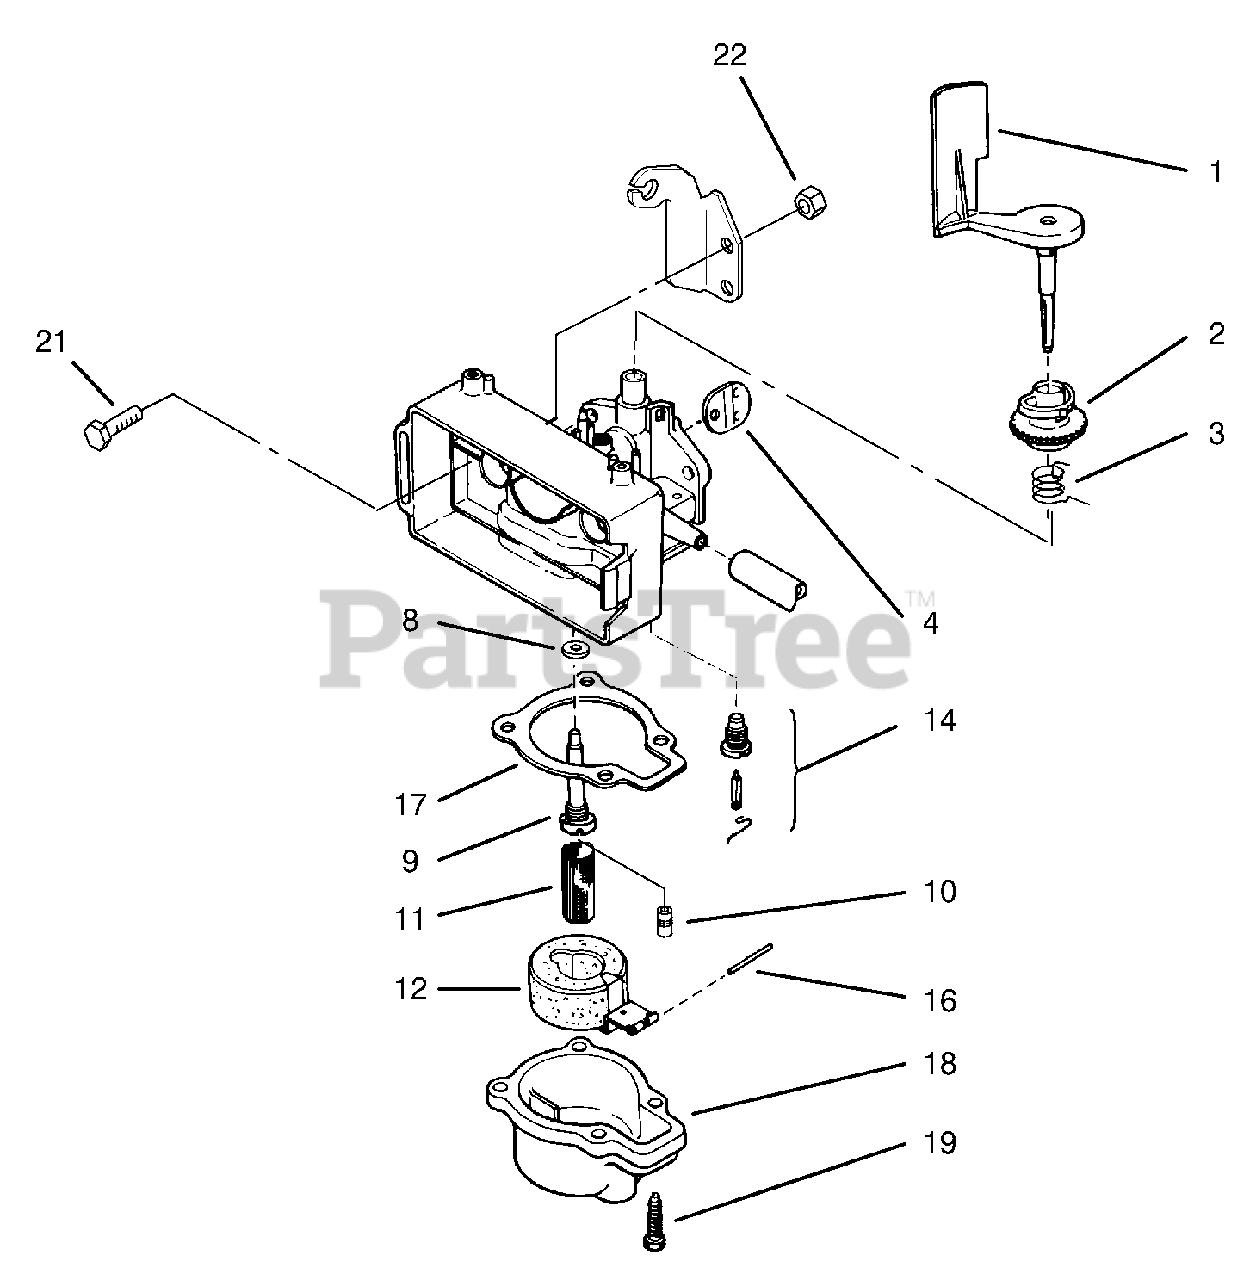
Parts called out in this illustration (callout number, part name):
1	Airvane And Shaft
2	Collar-Adjust, Airvane
3	Spring-Throttle
4	Disc-Throttle V
8	Washer Xvs
10	Jet-Main
11	Filter-Fuel Vs
12	Float & Arm ASM
14	Valve/Seat-Float
16	Pin-Straight
18	Chamber-Float
19	Screw-HH
22	Nut-Hex
